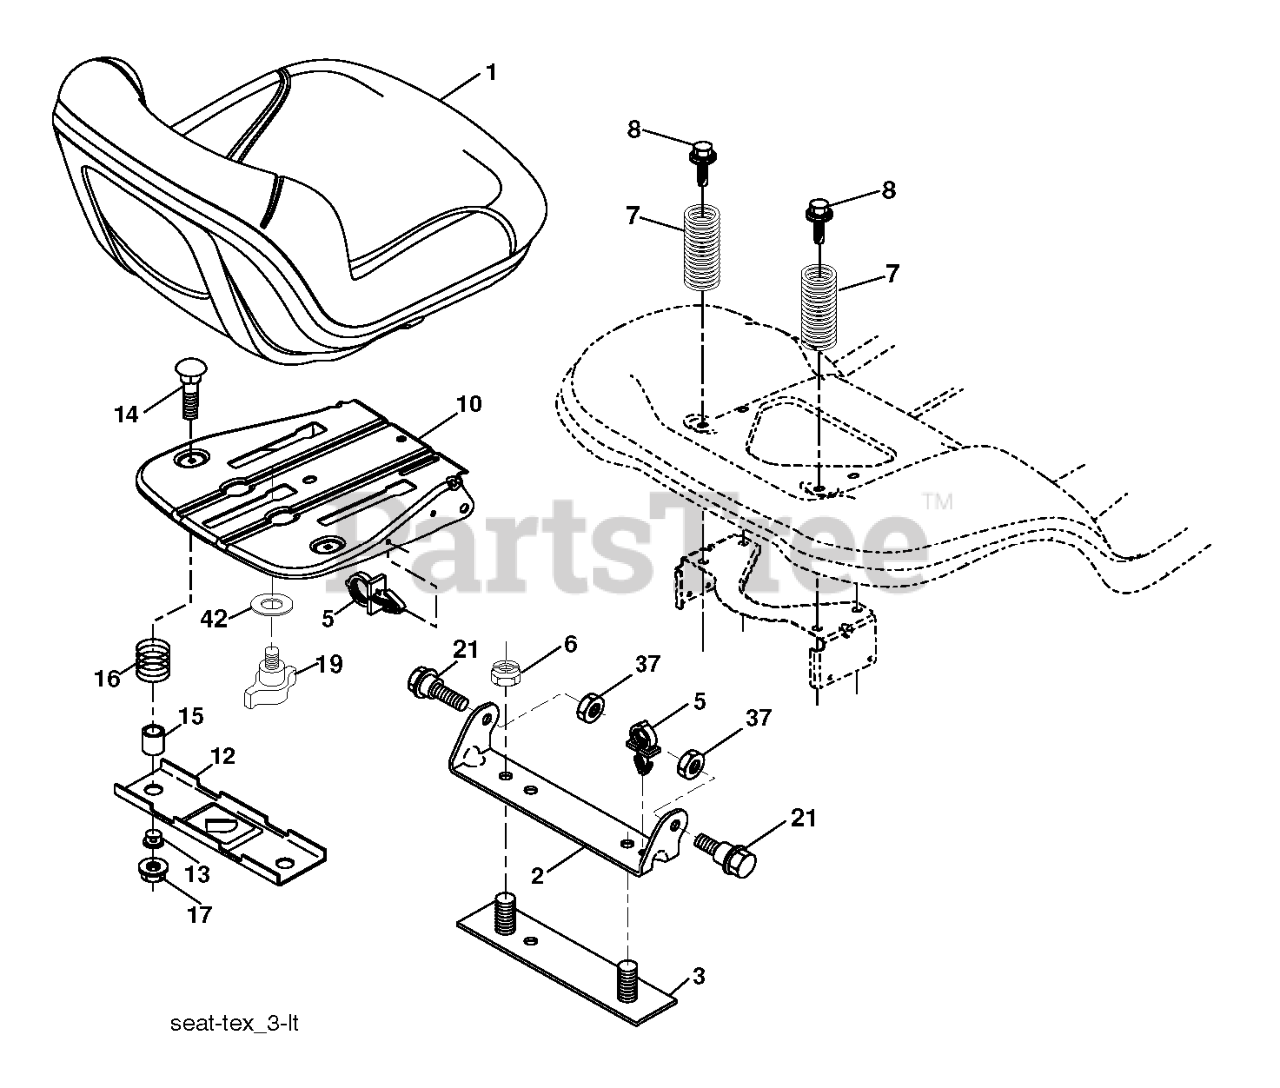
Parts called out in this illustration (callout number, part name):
1	SEAT.TH130.GRY.MILSCO.
2	BRKT.PIVOT.FENDER
3	STRAP
6	NUT
7	SPRING COMPRESSION
8	BOLT.5/16-18UNCX3/4 W/SEMS.BLK
10	PAN.ASM.SEAT.SHORT
12	BRKT.MNT.OPC.SW.SEAT.
14	BOLT.ROUND.HEAD.SQUARE.NECK
15	SPACER SPLIT 28X.96
16	SPRING COMPRESSED
17	NUT T
19	KNOB.SEAT.ADJ.
21	BOLT.SHOULDER.5/16-18
37	NUT.71038.31-18.HEX.NYLOCK
42	WASHER.CUP.SEAT.
